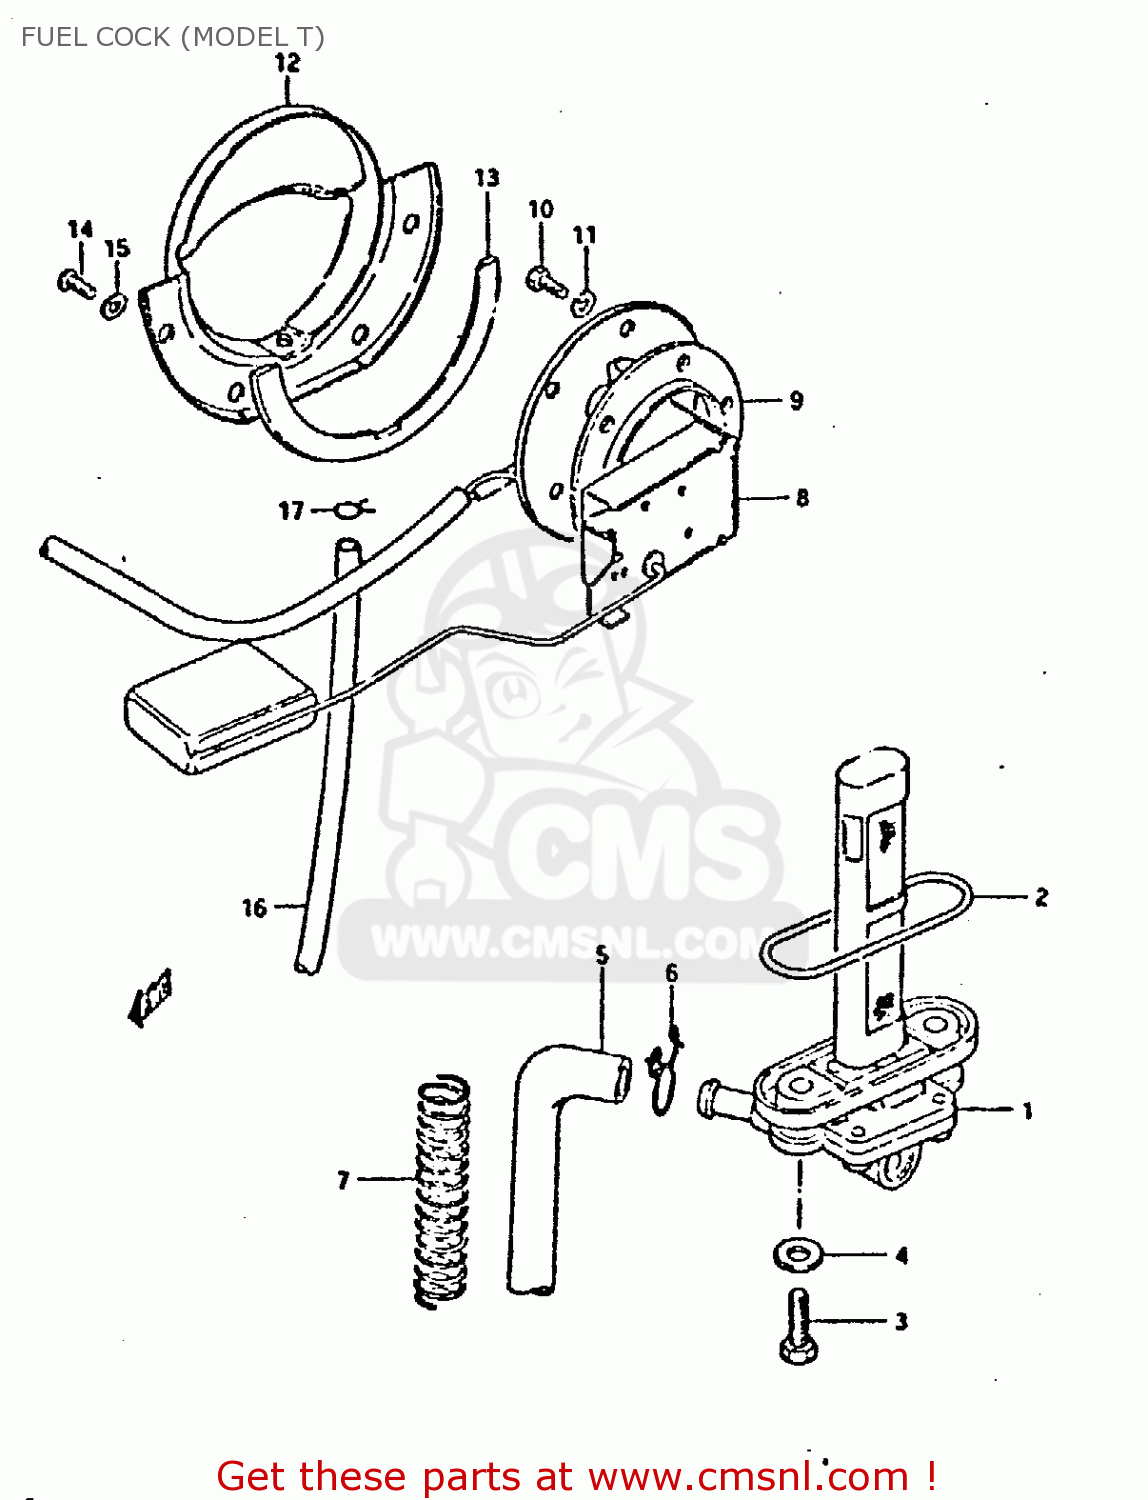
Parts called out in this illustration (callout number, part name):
1	COCK ASSY,FUEL
2	GASKET (NAS)
3	SCREW (6X25)
4	GASKET
5	HOSE
6	CLIP
7	SPRING
8	GAUGE, FUEL LEVEL (24L)
9	GASKET,FUEL LEVEL GAUGE (NAS)
10	BOLT
11	LOCK WASHER
12	PLATE,FUEL DRAIN
13	GASKET,FUEL DRAIN PLATE (NAS)
14	SCREW
15	LOCK WASHER
16	HOSE,FUEL
17	CLIP
